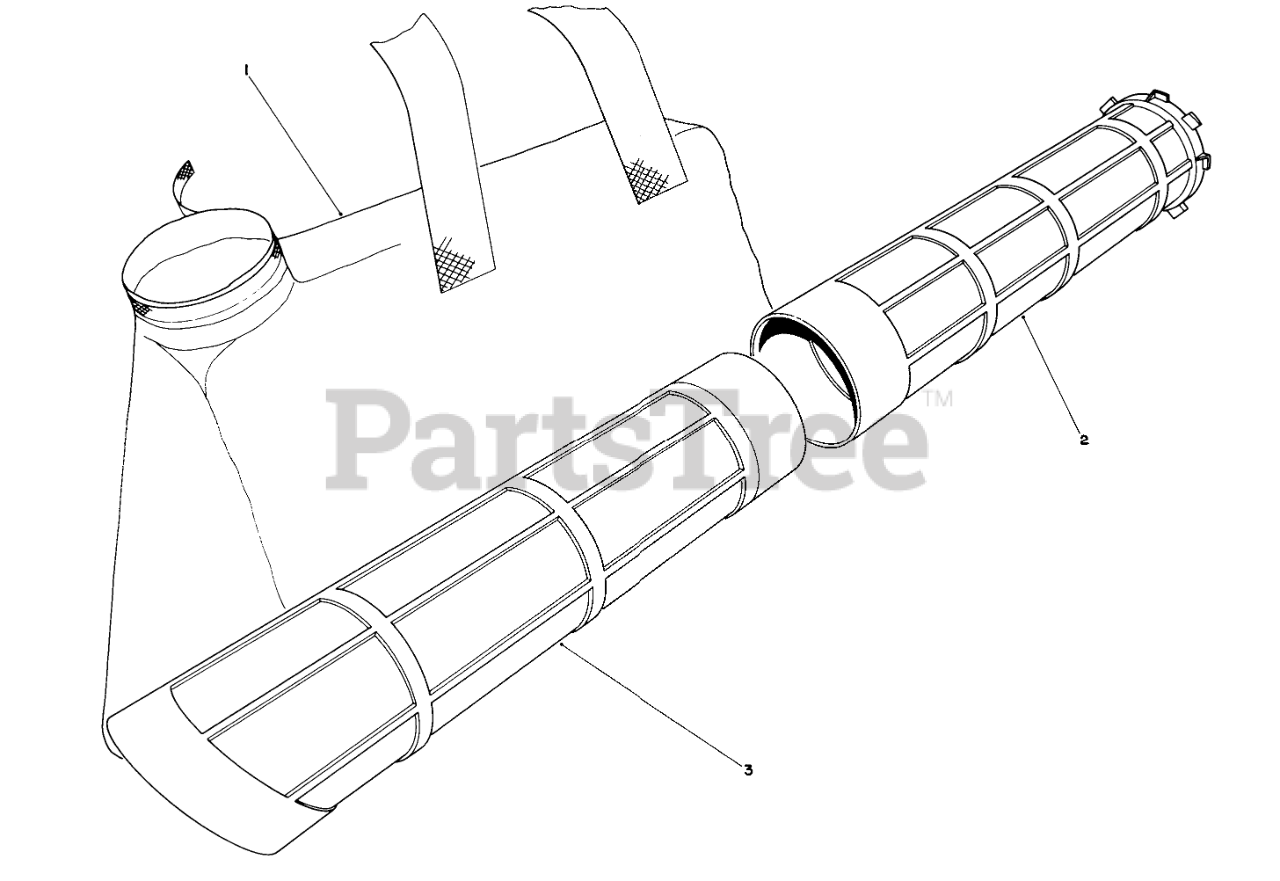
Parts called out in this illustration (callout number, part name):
1	Bag-Vacuum
2	Tube-Upper Vacuum
3	Tube-Lower Vacuum
